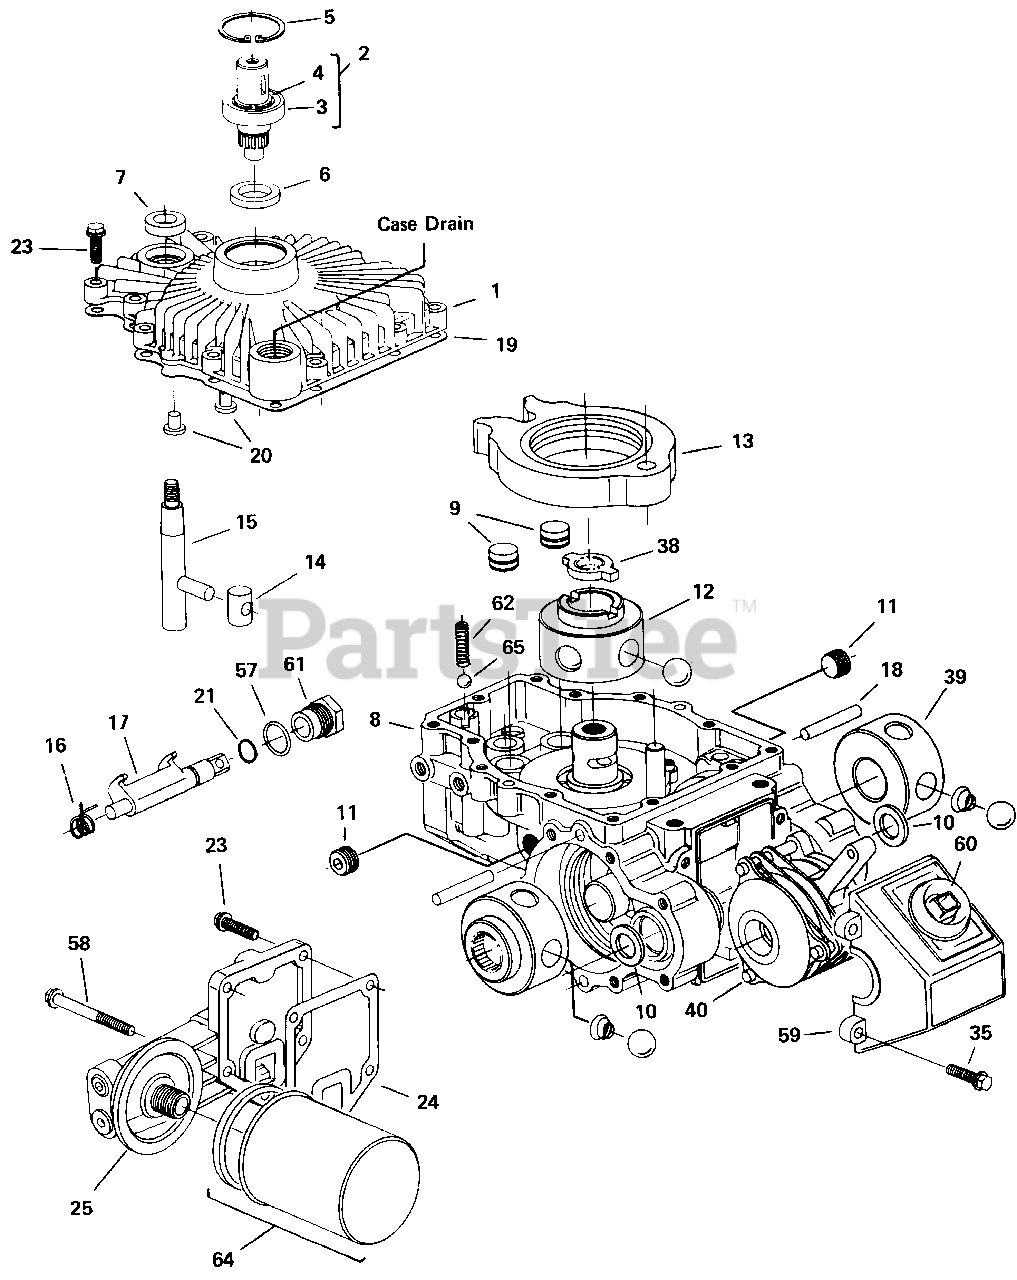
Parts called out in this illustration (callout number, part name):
1	COVER, Subassembly (S/A)
2	SHAFT, Input, S/A (Incl. 3 & 4)
3	BEARING
4	RING
5	RING, Retaining, Internal
8	HOUSING, S/A, Clockwise
9	PISTON, Quieting, S/A
10	SEAL, Lip, Radial
11	PLUG, Socket Pipe
12	PUMP, Rotor-Ball Pin, S/A
13	CAM RING, S/A
15	CONTROL SHAFT, S/A
16	SPRING, Dump valve
19	GASKET, Cover
23	CAPSCREW, Hex, Flange, 1/4-20
24	GASKET, Filter Base
25	FILTER BASE, S/A
35	SCREW, 1/4-20 Self Tap
39	MOTOR ROTOR-BALL, A & B S/A, 15T
40	BRAKE, Parking, Assembly
57	O-RING, Fitting
58	SCREW, 1/4-20 Hex Flange
59	COVER, Parking Brake
62	SPRING, Relief Valve
64	FILTER, Oil (w/Seal), Special-10 Micron
65	BALL, Grade 200
65	GASKET OVERHALL KIT (Incl. Ref. Nos. 19, 22 & 24)
